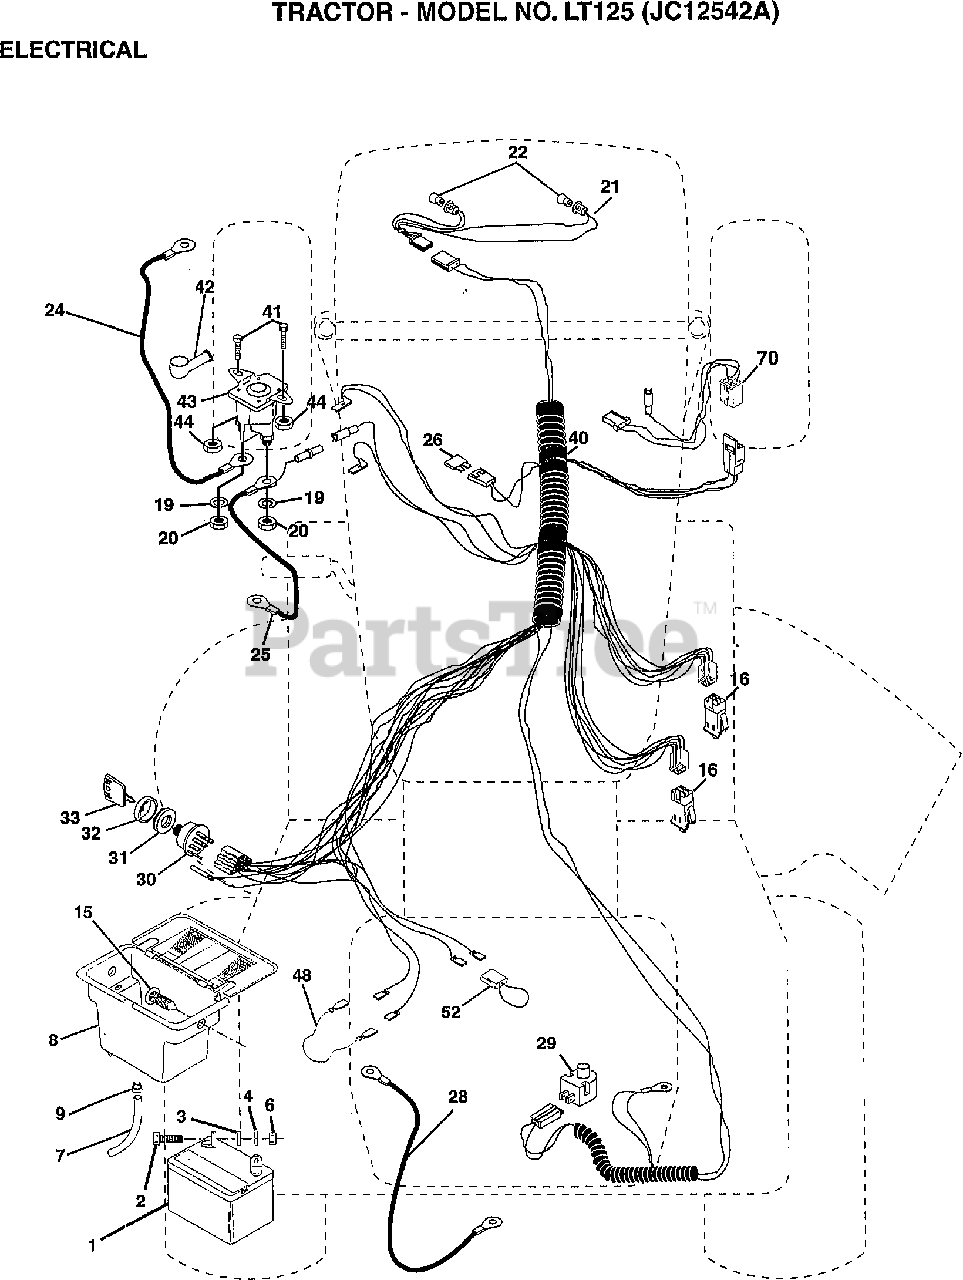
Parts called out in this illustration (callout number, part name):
2	BOLT HEX HD 1/4-20 X 3/4
3	WASHER 9/32 X 5/8 X 16 GA.
4	WASHER, LOCK 1/4
6	NUT, HEX 1/4-20
19	WASHER LOCK 1/4
20	NUT JAM HEX 1/4-20 UNC
41	BOLT BLK FIN HEX 1/4-20 X 1/2
44	NUT KEPS HEX 1/4-20 UNC
